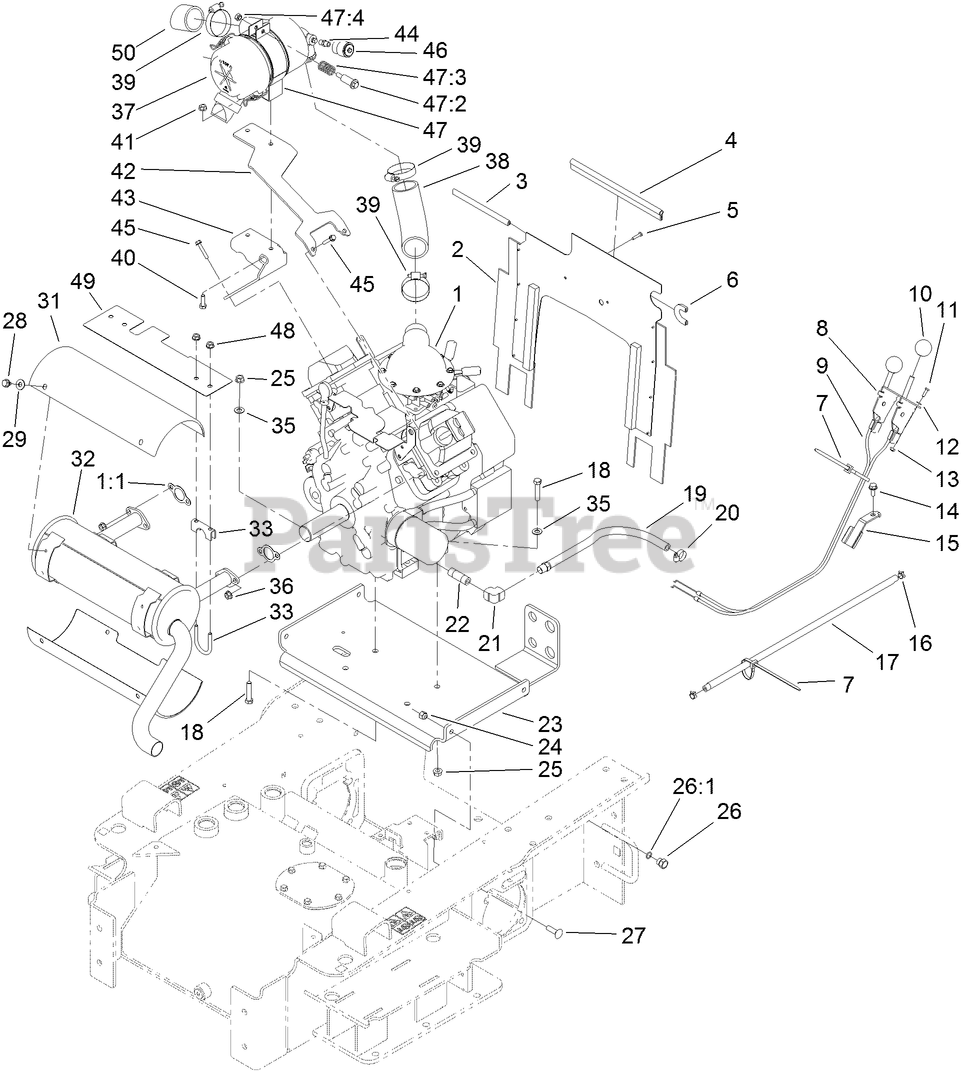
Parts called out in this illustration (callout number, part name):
1:1	GASKET-EXHAUST
2	BAFFLE-ENGINE
3	SEAL-STRIP, 6.5 INCH
4	STRIP-SEAL, 10.5 INCH
5	SCREW-PPH
6	SEAL-STRIP, 3 INCH
7	TIE-CABLE
8	LEVER-CONTROL
9	CABLE-THROTTLE/CHOKE
12	WASHER-FLAT
13	NUT-KEPS
14	SCREW-HWHTF
15	GUIDE-CABLE
16	CLAMP-HOSE
17	HOSE-FUEL
18	SCREW-HH
19	OIL HOSE ASM
20	CLAMP-HOSE
21	ELBOW-90 DEG
22	NIPPLE
23	PLATE-MOUNTING, ENGINE
24	NUT-LOCK, NI
25	NUT-HF
26	PLUG-HH
26:1	O-RING
27	SCREW-CARR
28	SCREW
29	WASHER-FLAT
31	SHIELD-MUFFLER
32	MUFFLER
33	CLAMP-MUFFLER
35	WASHER-PLAIN
36	NUT-HF
37	AIR CLEANER ASM
38	HOSE-AIR CLEANER
39	CLAMP-HOSE
40	SCREW-HH
41	NUT-HF
42	BRACKET-SUPPORT, LEFT
43	BRACKET-SUPPORT, RIGHT
44	Nipple-Pipe
45	SCREW-HHF
46	INDICATOR-MINI
47	AIR CLEANER MOUNTING BAND ASM
47:3	SPRING
47:4	NUT
48	NUT-HF
49	SHIELD-MANIFOLD
50	TUBE-INLET, AIR
